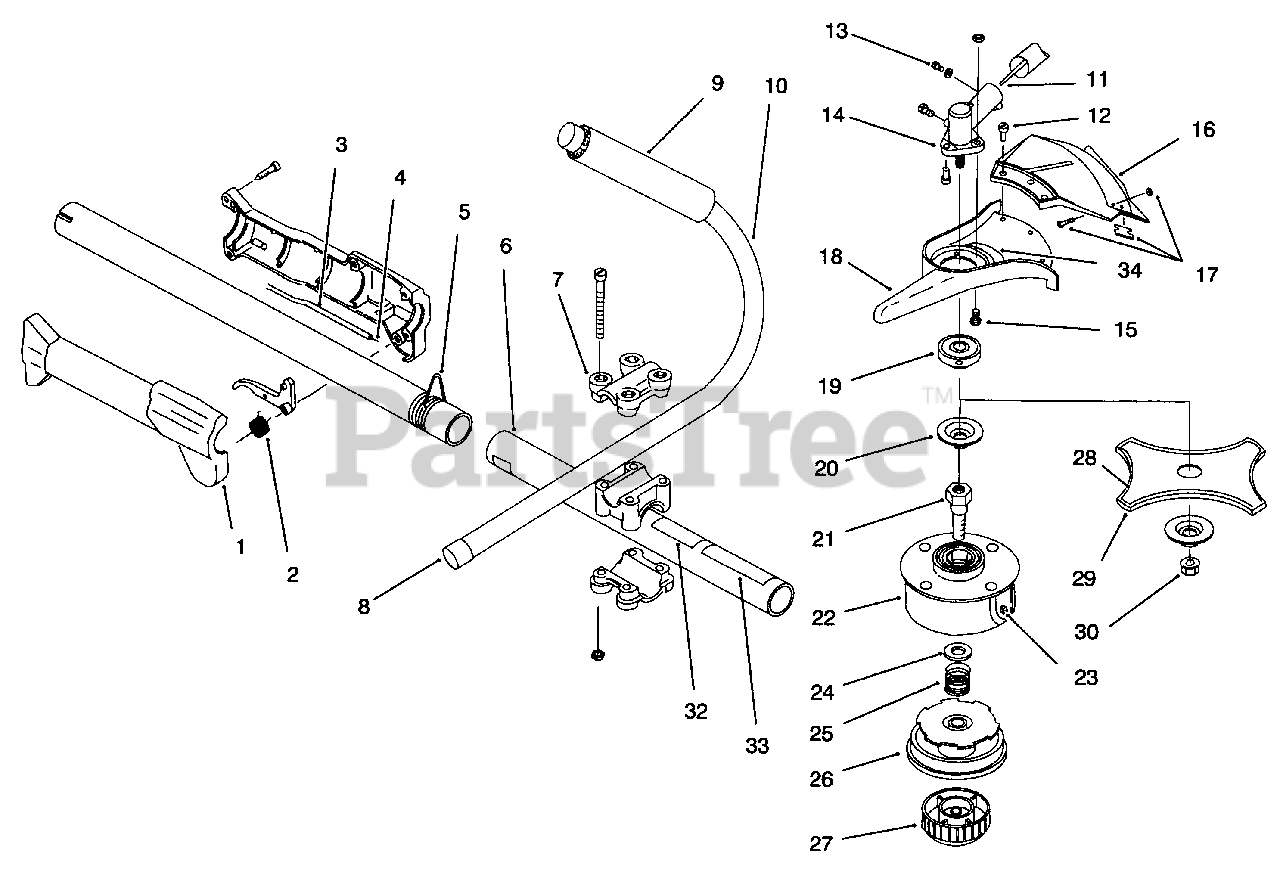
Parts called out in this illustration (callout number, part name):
1	Throttle Housing & Trigger Asm.
2	Throttle Trigger Spring
3	Throttle Cable Housing
4	Throttle Cable
5	Shoulder Strap Clamp
6	Driv Shaft Housing Asm.
7	Handle Bracket Asm.
8	Tube Closure
10	J-Handle Asm. (Incl. Ref. #8-9)
11	Flexible Drive Shaft
12	Guard Mounting Screws
13	Mounting Hardware & Grease Plug Asm.
14	Gear Box Asm. (Incl. Ref. #13, 19, 20, 30)
15	Guard Mounting Screws
16	Guard and Blade Asm. (Incl. Ref. #17)
17	Blade Asm.
18	Guard Mount
19	Blade Drive
20	Blade Retaining Washer
21	Spool Shaft
22	Outer Spool & Eyelet Asm.
24	Retainer
26	Inner Reel
27	Bump Head Knob Asm.
28	Blade
29	Blade Cover
30	Lock Nut
32	Decal-Safety Symbols
33	Decal-Safety
34	Decal-Warning
